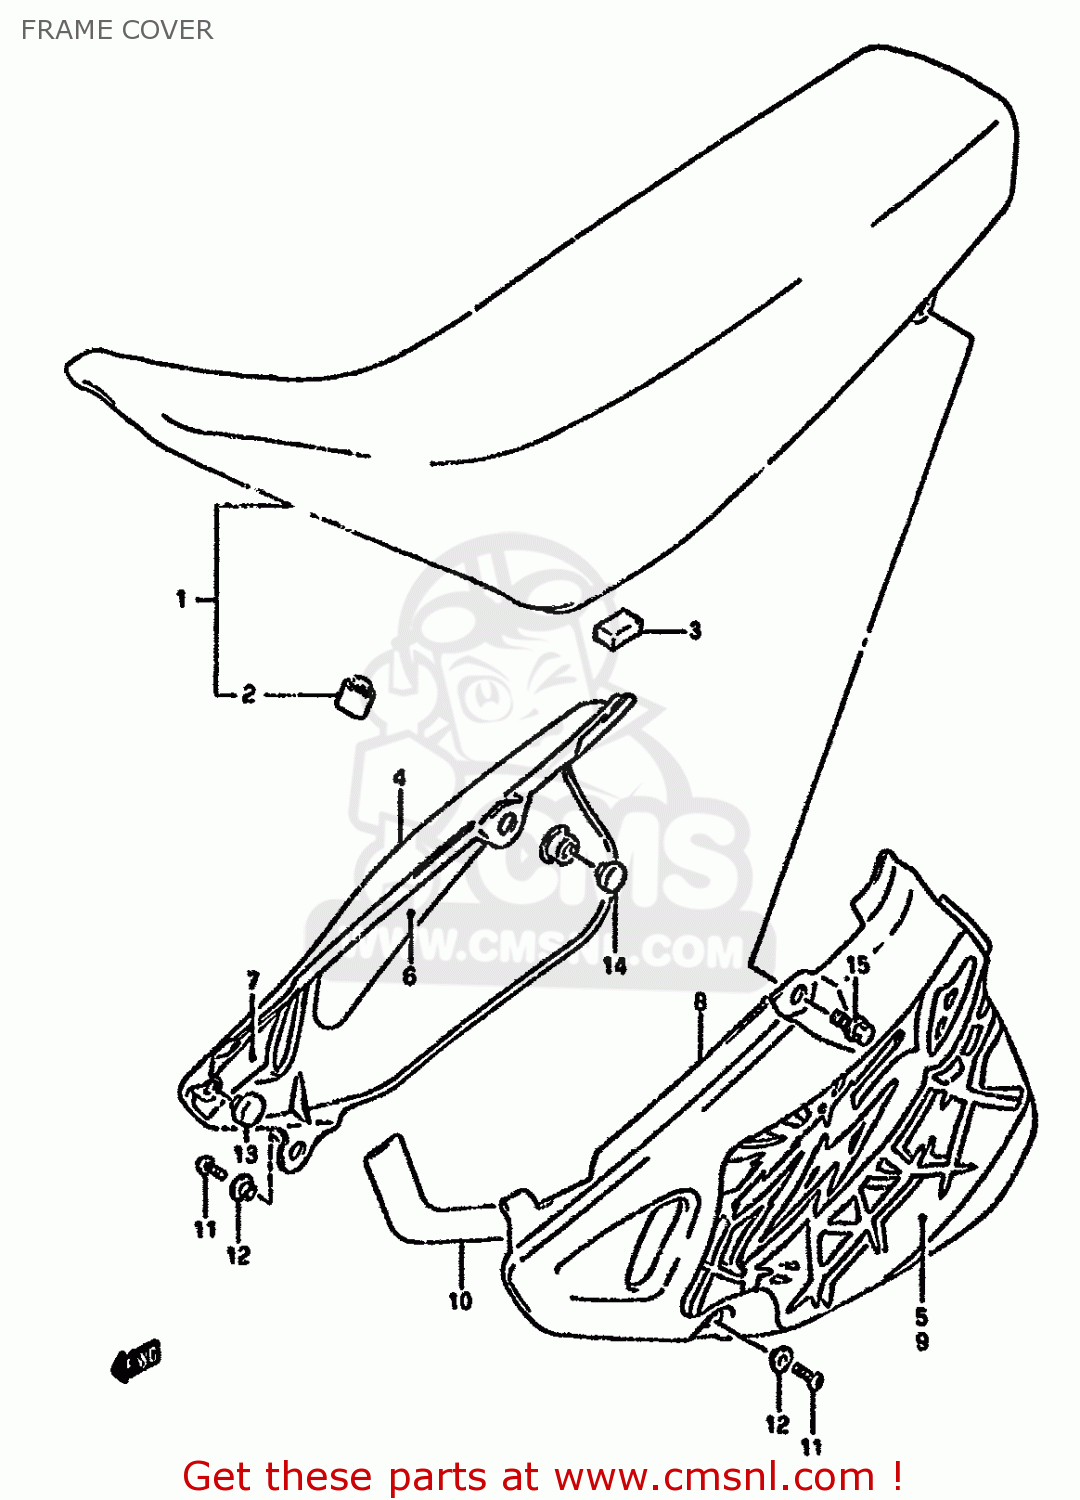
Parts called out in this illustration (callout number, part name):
1	SEAT ASSEMBLY
2	CUSHION
3	CUSHION,SEAT
4	COVER,FRAME,R(WHITE)
5	EMBLEM,FRAME COVER RH
6	SHIELD,FRAME COVER,R HEAT
7	SHIELD,FRAME COVER,R NO.2
8	COVER,FRAME,L(WHITE)
9	EMBLEM,FRAME COVER LH
10	CUSHION,FRAME COVER LH
11	BOLT
12	WASHER
13	CUSHION
14	CUSHION
15	BOLT
